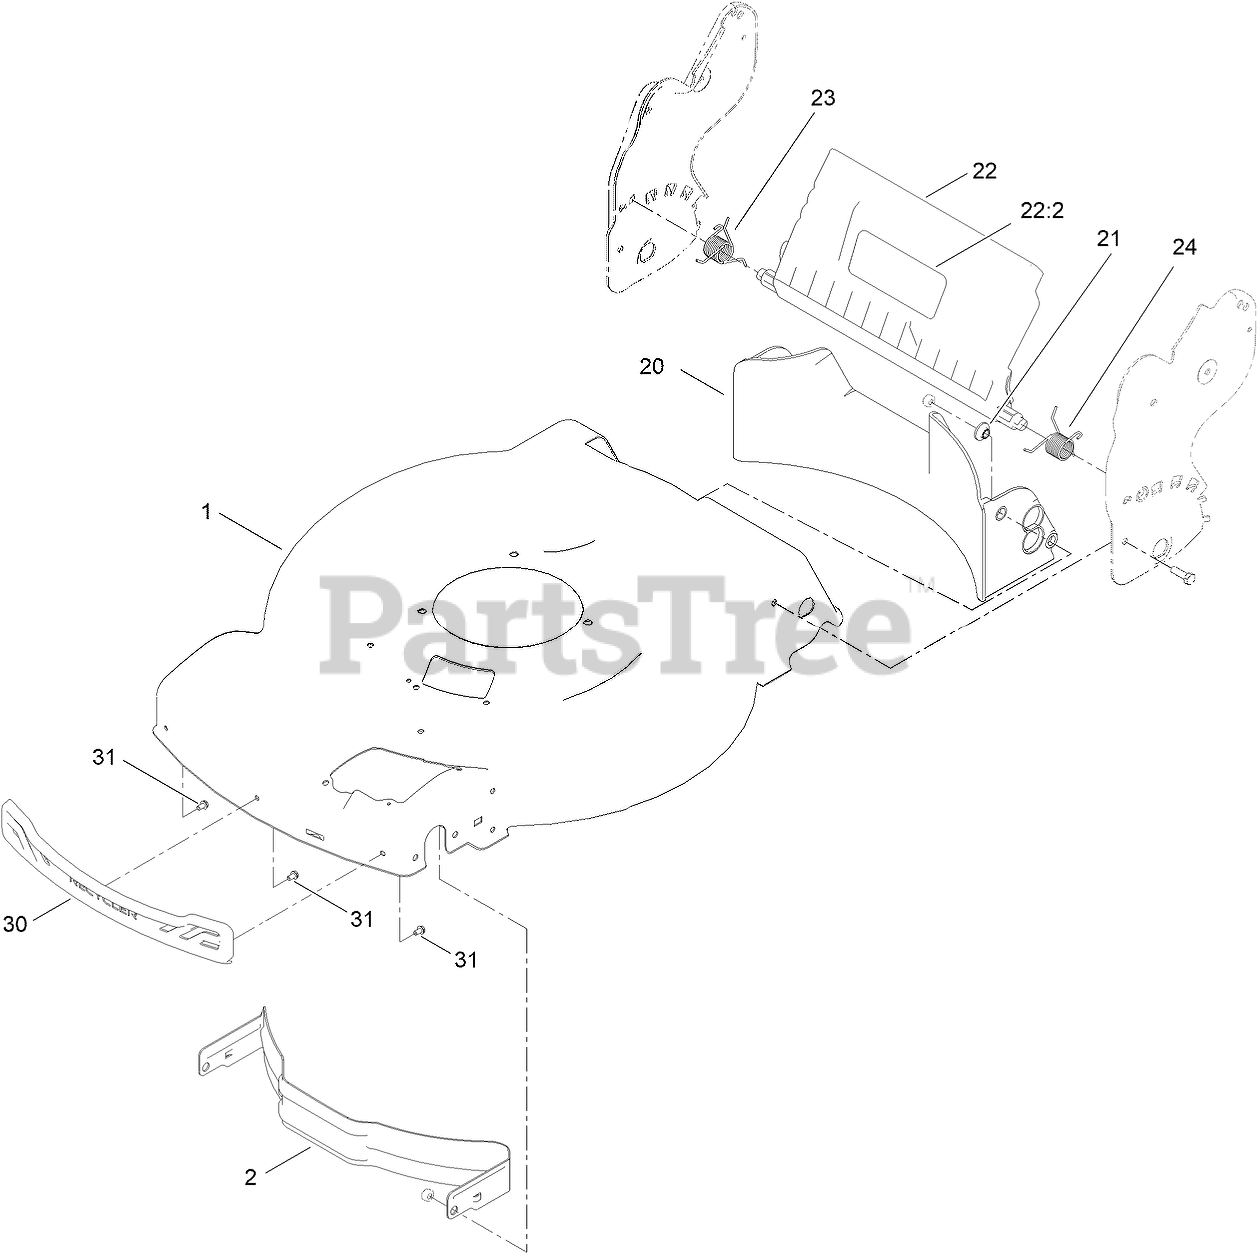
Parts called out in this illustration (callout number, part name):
1	HOUSING ASM
2	BAFFLE-FRONT
20	BAFFLE-REAR, FWD
21	WASHER-STEPPED, BAFFLE
22	REAR DEFLECTOR ASM
22:2	DECAL-WARNING
23	SPRING-TORSION
24	SPRING-TORSION
30	BUMPER-FRONT
31	SCREW-PLASTIC, HWH
